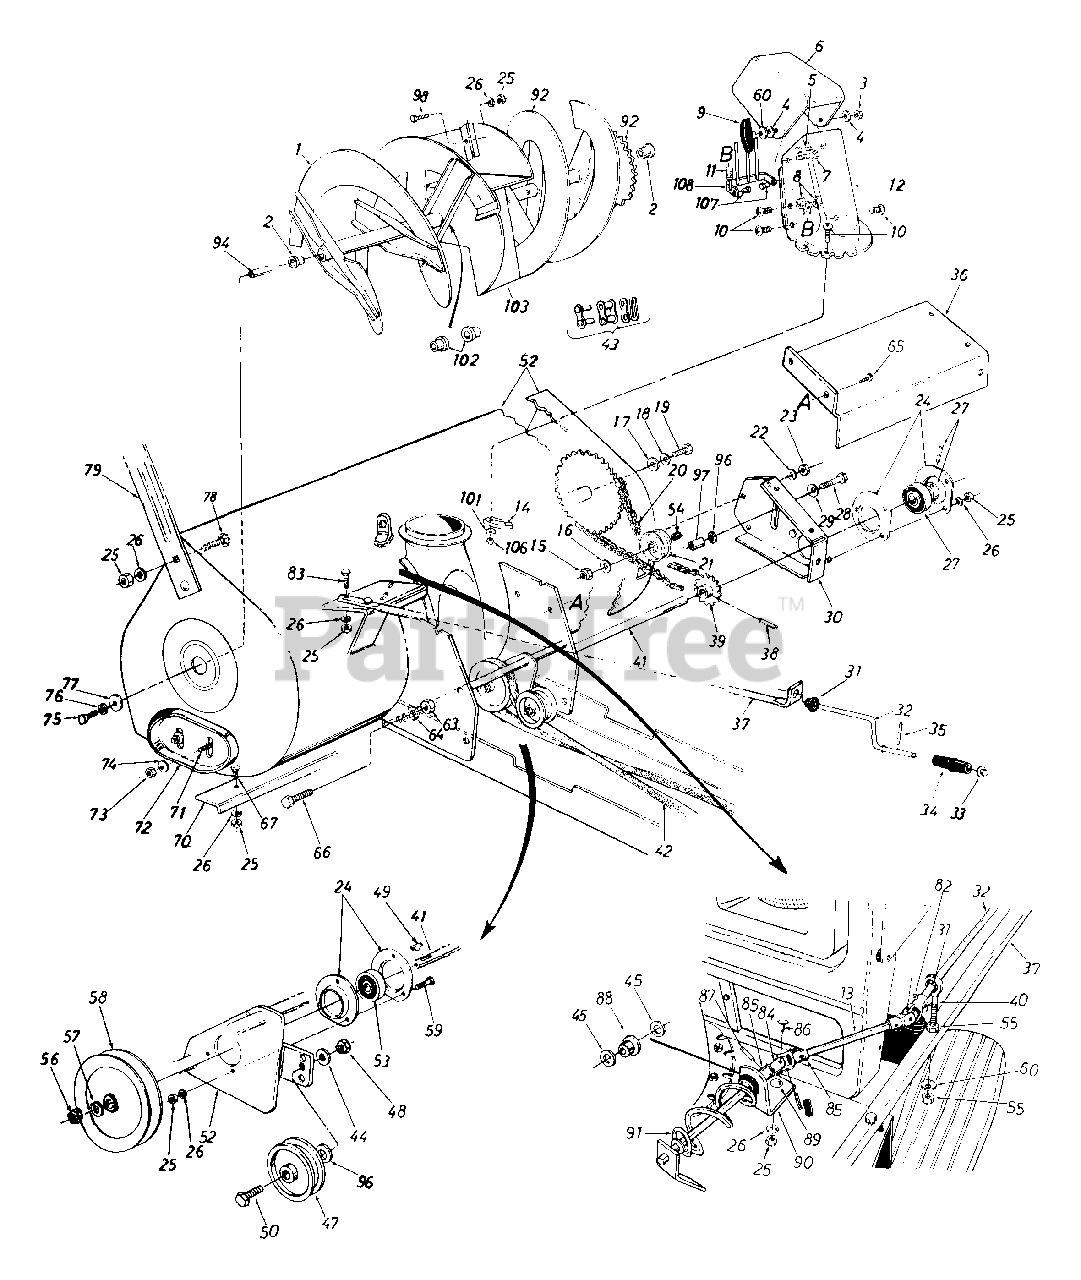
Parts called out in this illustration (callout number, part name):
1	Spiral Ass'y. (L.H.)
2	Flange Bearing
3	Hex L-Nut 5/16-18 Thd.
4	Fl-Wash. .344" I.D.
5	Truss Mach. Scr. 5/16-18 x .75" Lg.
6	Upper Chute
7	Carriage Bolt 5/16-18 x 1.0" Lg.
8	Hex L-Nut 1/4-20 Thd.
9	Hand Knob
10	Truss Mach. Scr. 1/4-20 x .75" Lg.
11	Ext. Spring
12	Lower Chute
13	Chute Crank Extension Rod
14	Chute Flange Keeper
15	L-Nut 3/8-16 Thd.
16	Fl-Wash.
17	Fl-Wash.
18	Belleville Wash.
19	Hex Bolt 1/2-13 x 1" Lg.
20	#420 Chain 1/2" Pitch x 77 Links
21	Plastic Idler 2" O.D.
22	L-Wash. 1/4" I.D.
23	Hex Nut 1/4-20 Thd.
24	Bearing Housing
25	Hex Nut 5/16-18 Thd.
26	L-Wash. 5/16" I.D.
27	Self-Aligning Bearing
28	Hex Bolt 3/8-16 x 1.75" Lg.
29	Belleville Wash. 3/8" I.D.
32	Chute Crank .375" Dia. x 34.5" Lg.
33	Push Nut 3/8" Rod
34	Knob (Black)
35	Roll Pin
39	14 Teeth Sprocket Ass'y.
40	Eyebolt 5/16-18 x 3.0" Lg.
41	Drive Shaft
42	V-Belt
43	Master Link for #420 Chain
44	L-Wash. 3/8" I.D.
45	Fl-Wash. .385" I.D. x .62" O.D.
47	Fl-Idler with Flanges
48	Hex Jam L-Nut 3/8-16 Thd.
49	#61 Hi-Pro Key 3/16 x 5/8 Dia.
50	Hex Bolt 3/8-16 x 1.75" Lg.
52	Spiral Housing Ass'y.
53	Self-Aligning Bearing
54	Sleeve Bearing .50" I.D.
55	Hex Nut 5/16-18 Thd.
56	Hex Nut 3/4-10 Thd.
57	L-Wash. 3/4" I.D.
58	V-Pulley .750" I.D. x 6" O.D.
59	Hex Sems Bolt 5/16-18 x .75" Lg.
60	Bell-Wash. .345" I.D. x .88" O.D.
63	Hex Nut 1/2-13 Thd.
64	L-Wash. 1/2" I.D.
65	Hex Self-Tap Scr. 1/4-20 x .5" Lg.
66	Hex Bolt 1/2-13 x 2.75" Lg.
67	Carriage Bolt 5/16-18 x .75"
72	Skid Shoe
73	Hex Jam Nut 3/8-16 Thd.
74	Belleville Wash. 3/8" I.D.
75	Hex Bolt 1/2-13 x 1" Lg.
76	Belleville Wash. 1/2" I.D.
77	Fl-Wash.
78	Carriage Bolt 5/16-19 x .62" Lg.
79	Drift Cutter
82	Cotter Pin
83	Hex Bolt 5/16-18 x 1.5" Lg.
84	Joint Block
85	Joint Bracket Ass'y.
86	Oval Head Rivet
87	Spring Pin Roll 1/8" Dia. x .75" Lg.
88	Nylon Bushing
89	Carriage Bolt 5/16-18 x .75" Lg.
90	Chute Crank Bracket
91	Chute Crank Ass'y.
92	Spiral Ass'y. (R.H.)
94	Spiral Axle
96	Flat Washer
97	Idler Spacer
98	Carriage Bolt 5/16-18 x .75" Lg.
101	Fl-Wash. 1/4" I.D.
102	Plastic Bushing
103	Rotor Paddle Ass'y.
106	Hex L-Nut 1/4-20 Thd.
107	Shld. Nut 1/4-20 Thd.
108	Chute Guard Ass'y.
